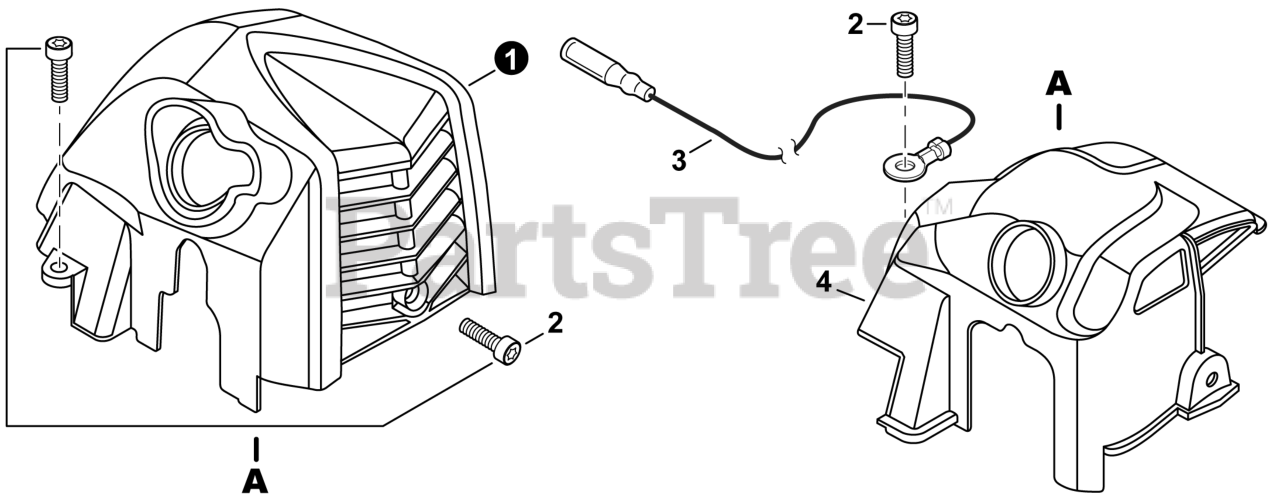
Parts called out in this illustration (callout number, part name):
1	COVER, ENGINE
2	BOLT, TORX 5×12
4	COVER, CYLINDER
